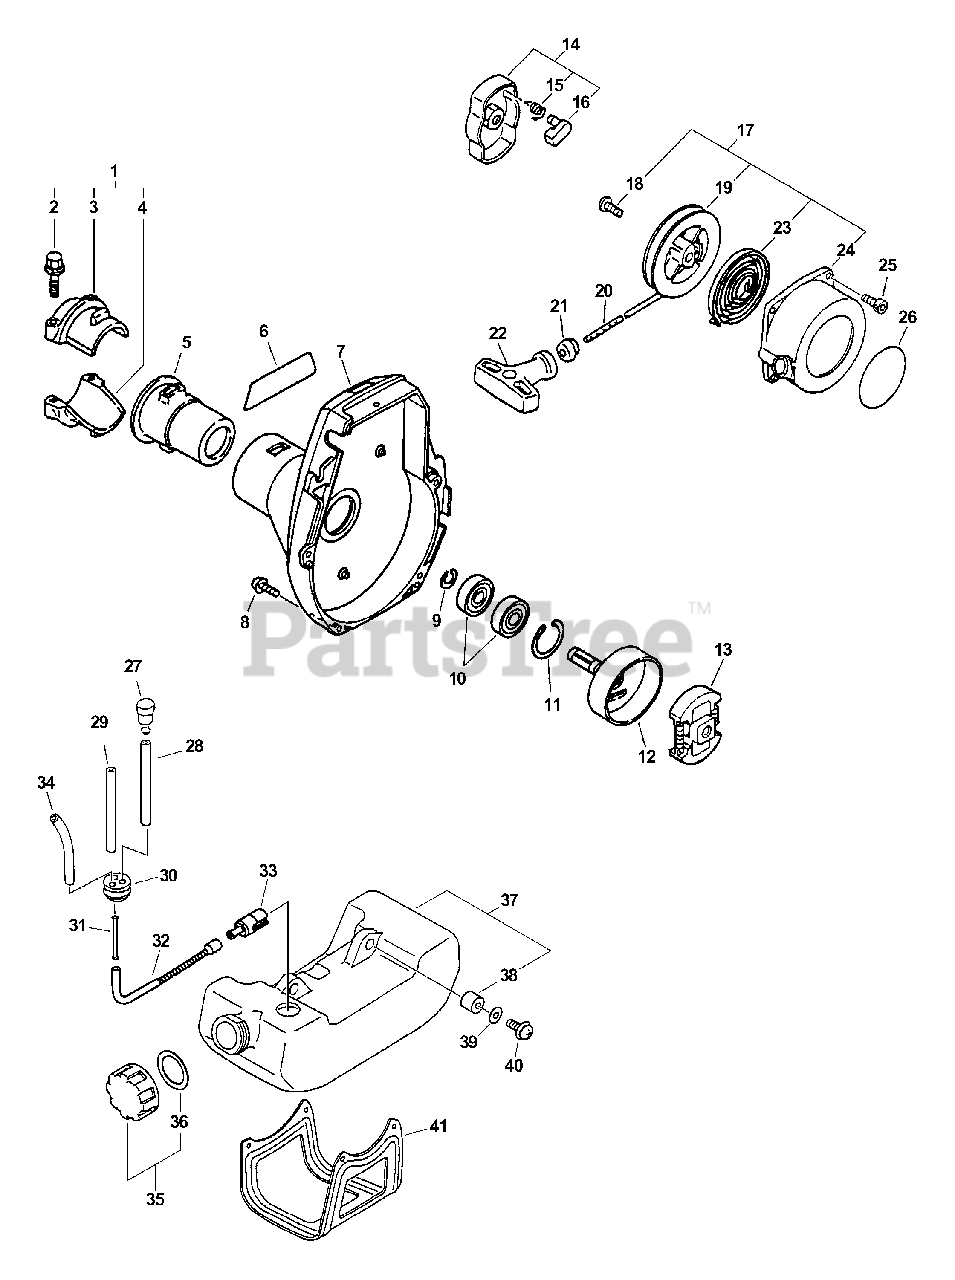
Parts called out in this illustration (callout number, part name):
1	MAIN PIPE CLAMP KIT
2	BOLT - 5X25
3	CLAMP, MAIN PIPE - UPPER
4	CLAMP, MAIN PIPE - LOWER
6	LABEL - MODEL SHC-2400
7	CASE, FAN
8	SCREW - 4X16
9	RING, RETAINING - 12
10	BEARING, BALL - 6001
11	RING, RETAINING - 28
12	DRUM, CLUTCH
13	CLUTCH ASSY
14	STARTER PAWL ASSY
15	SPRING, RETURN
16	PAWL, STARTER - BLACK
17	STARTER ASSY
19	REEL, ROPE
20	ROPE, STARTER - 3X1000
21	GUIDE, ROPE
22	GRIP, STARTER
23	SPRING, REWIND
24	CASE, STARTER
25	SCREW - 4X16
26	LABEL - ECHO
27	VENT, FUEL TANK
28	PIPE - 3X5X70 -- BLACK
29	PIPE - 3X5X70 -- BLACK
30	GROMMET
31	CONNECTOR, PIPE
32	PIPE, FUEL - CORRUGATED
33	FILTER, FUEL
34	PIPE - 3X6X90 -- CLEAR
35	CAP ASSY
36	GASKET, CAP
37	FUEL TANK ASSY
39	WASHER - 5
40	SCREW - 5X16
41	GUARD, FUEL TANK
